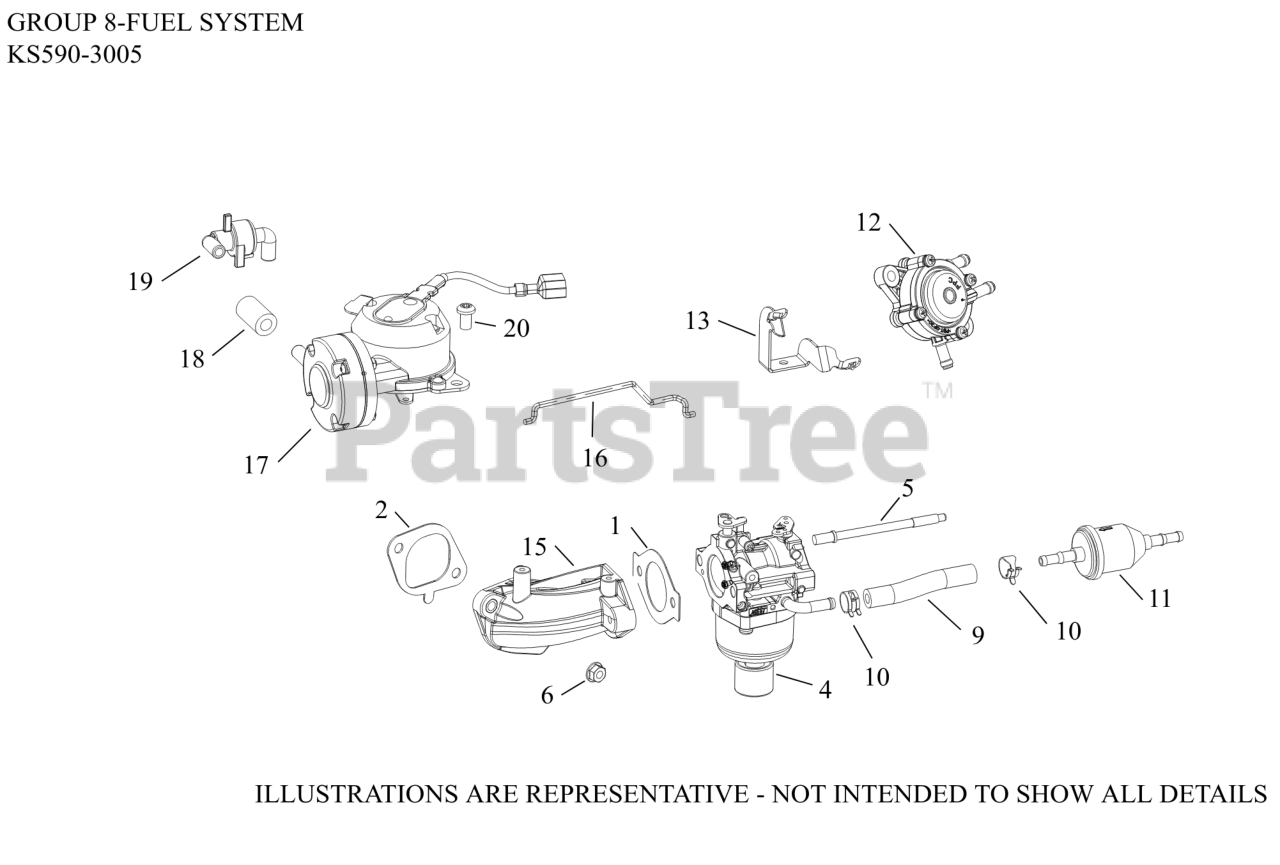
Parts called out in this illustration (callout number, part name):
1	GASKET, CARBURETOR (THROTTLE)
2	GASKET, INTAKE MANIFOLD
4	KIT,CARB(NIKKI)
5	STUD, CARBURETOR
6	NUT, FLG M6X1.0
9	HOSE,LW PERM.FUEL 24.00"-USE 25 111 81-S
10	SPRING CLAMP, HOSE
11	FILTER,FUEL 51 MICRON (FUEL PUMP)
12	PUMP, FUEL (PULSE)-(#2539326S)
13	BRACKET, FUEL PUMP
15	MANIFOLD, INTAKE ASSY
16	LINKAGE, CHOKE
17	DIAPHRAGM ASSY
18	HOSE, VACUUM
19	CHECK VALVE ASSY
20	SCREW, K40 X 1.79 TFS
NI	HIGH ALTITUDE KIT (5000 FT)
NI	KIT, OVERHAUL
NI	KIT, CHOKE SHAFT
NI	KIT, O-RING
NI	KIT, SOLENOID (NIKKI)
NI	KIT, BOWL WITH O-RINGS
NI	KIT, FLOAT & INLET NEEDLE FOR FUEL PUMP
NI	KIT, THROTTLE SHAFT
